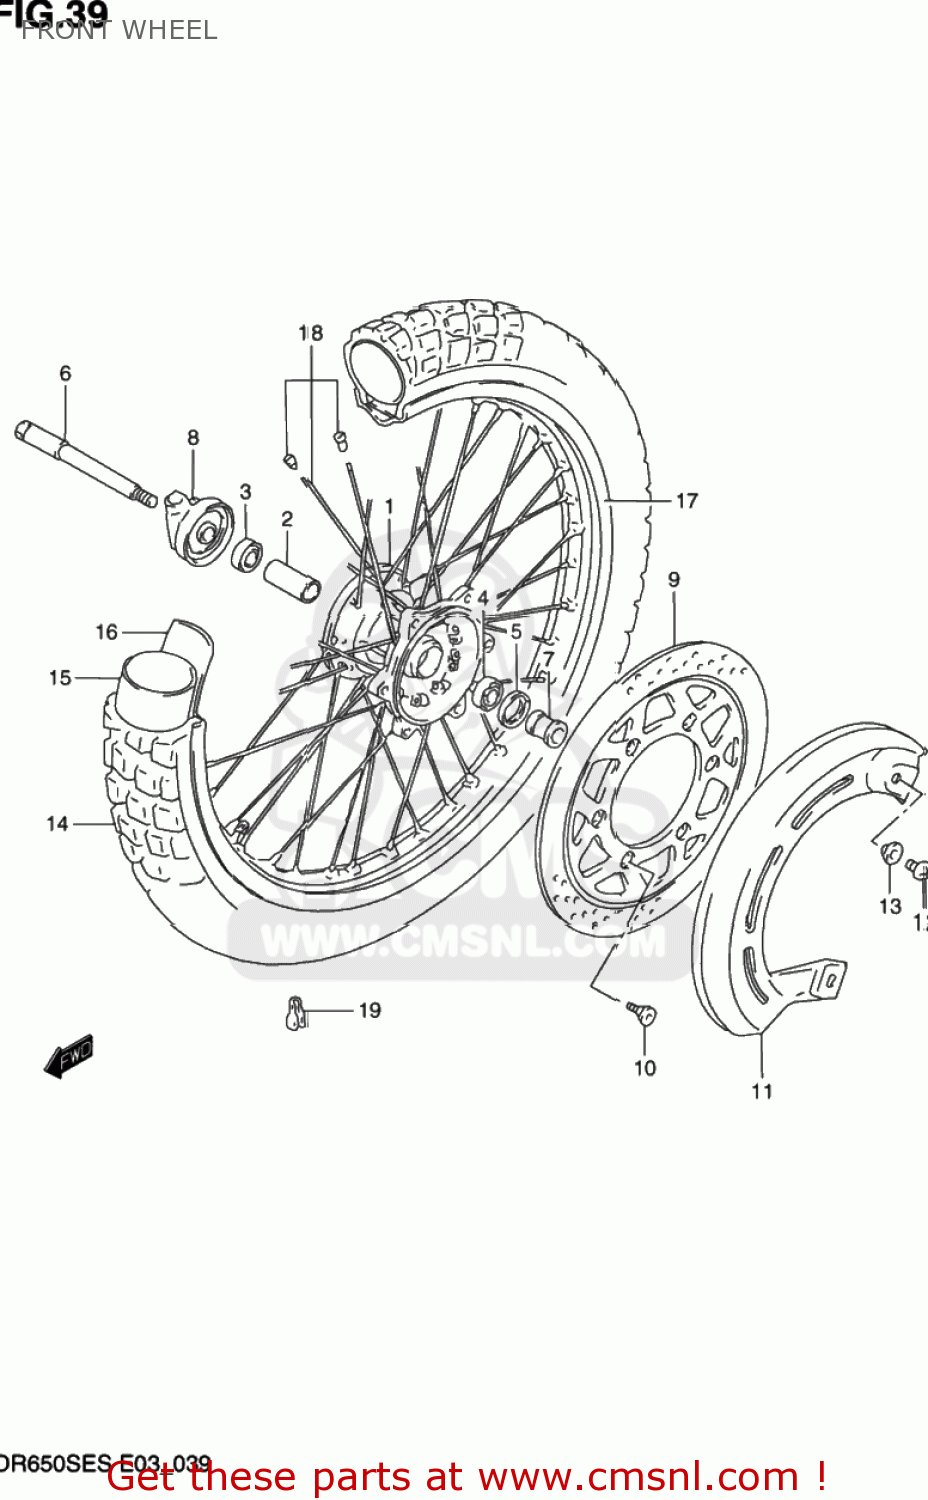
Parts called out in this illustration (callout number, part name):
1	HUB,FRONT WHEEL
2	SPACER,FR HUB BEARING
3	BEARING
4	BEARING
5	SEAL,OIL(22X35X5)
6	AXLE,FR
7	SPACER,FR AXLE,L
8	BOX ASSY,SPEEDOMETER GEAR
9	DISC,FR BRAKE
10	BOLT,BRAKE DISC
11	COVER,FR BRAKE DISC
12	SCREW 6X12
13	WASHER
14	TIRE,FRONT 90/90-21 54
15	TUBE
16	PROTECTOR,WHEEL INNER
17	RIM,FR WHEEL(21X1.85)
18	SPOKE SET,FR WHEEL
19	BALANCER,WHEEL
